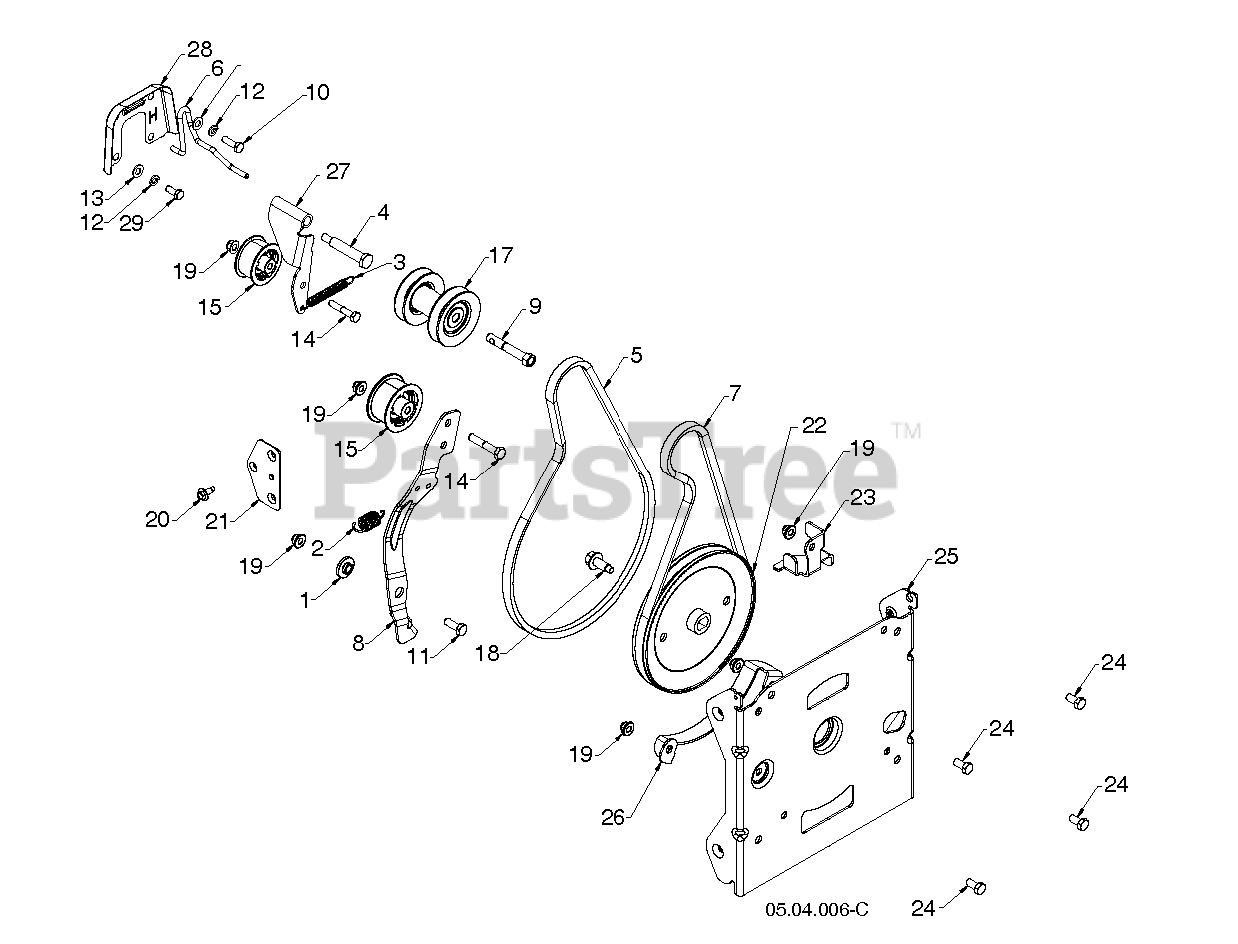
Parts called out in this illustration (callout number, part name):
1	BUSHING.BRAKE.ARM
2	SPRING RETURN, IDLER ARM, IMPE
3	SPRING RETURN IDLER ARM
4	BOLT 5/16-24X2.25 HEX HEAD SHO
5	BELT 3L 39.68; POLY CORD
6	Belt Keepers
7	HIGH CRANK IMPELLER BELT
8	ARM.IDLER.AUTO-PH.676
9	BOLT.ENGINE.PULLEY
11	BOLT HEXAGON BOLT 5/16-18 X 7/
12	WASHER SPRING LOCK WASHER WITH
13	WASHER 11/32 X 11/16 X 14 GA T
14	BOLT, HEX 5/16-18X1-3/4
15	PULLEYIDLER.2.0.W/SPACER.CZ
18	SCREW HEXAGON HEAD FLANGE 3/8-
19	NUT HEXAGON FLANGE 5/16-18 ST
20	HEX.WASHER.HEAD 1/4-20 X .65
21	BRACKET NUT BLACK ZINC PLATE
22	PULLEY IMPELLER DD 4L
23	GUIDE.LOWER.AUGER.BELT.479
25	BRACKET.AUG.HOUSING.INTER.BLAC
26	BRACKET.BELT.KEEPER.LOWER.BLAC
27	ARM DRIVE IDLER CLEAR ZINC PLA
29	SCREW 5/16-24 X .75 GR5
